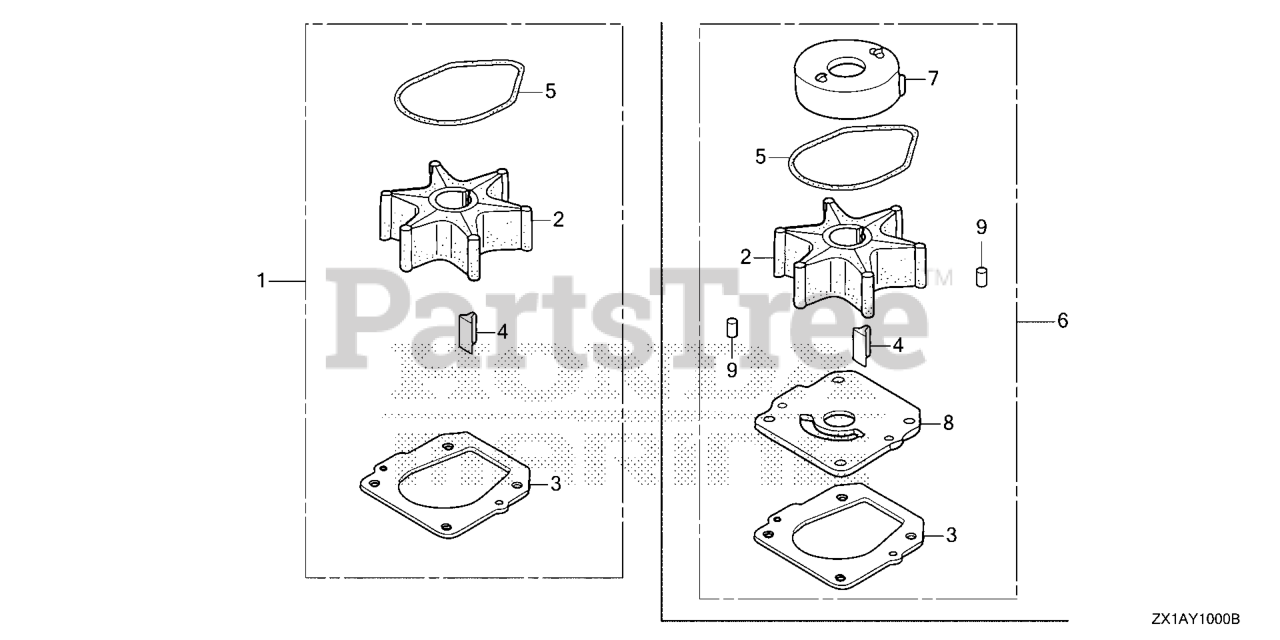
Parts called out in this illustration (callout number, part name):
1	PUMP KIT, IMPELLER
2	IMPELLER, PUMP
3	GASKET B, IMPELLER
4	KEY, WOODRUFF
5	O-RING, WATER PUMP
6	PUMP KIT, IMPELLER
7	LINER, PUMP
8	COVER, IMPELLER
9	PIN, DOWEL (6X10)
